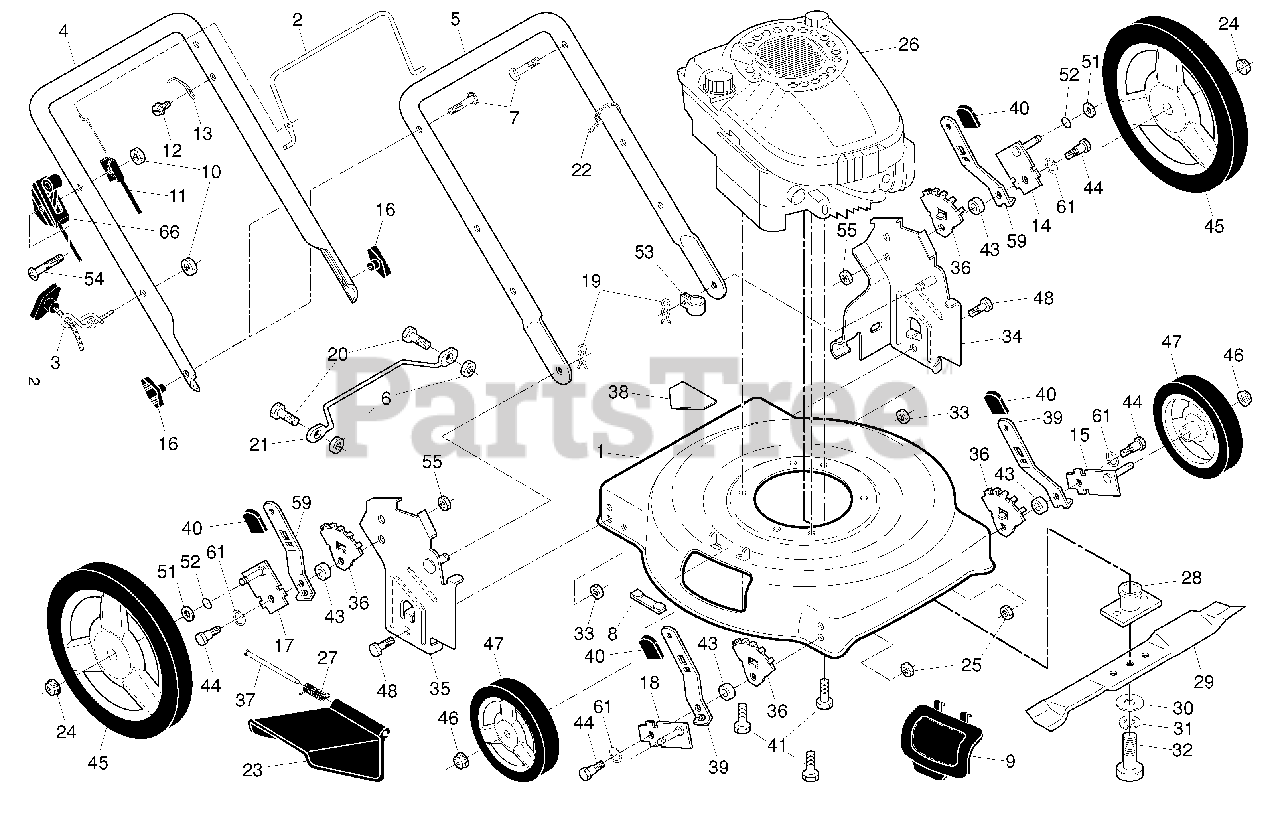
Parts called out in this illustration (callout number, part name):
1	Lawn Mower Housing
2	Control Bar
3	Rope Guide
4	Upper Handle
5	Lower Handle
6	Locknut, Hex 1/4-20
7	Handle Bolt 5/16-18
8	Clip, Closeout
9	Plate, Mulcher
10	Nut, Hex
11	Engine Zone Control Cable
12	Hex Thread Rolling Screw #10-24 x1/2
13	Up-Stop Bracket
14	Axle Arm Assembly (Rear, LH)
15	Axle Arm Assembly (Front, LH)
16	Handle Knob
17	Axle Arm Assembly (Rear, RH)
18	Axle Arm Assembly (Front, RH)
19	Hairpin Cotter
20	Hex Head Screw 1/4
22	Wire Tie
23	Discharge Guard
25	Nut, Hex
26	Engine, Briggs & Stratton, Model Number 122T02 (Order parts from engine manufacturer)
27	Torsion Spring
28	Blade Adapter
30	Hardened Washer
31	Helical Lockwasher 3/8
32	Hex Head Screw 3/8-24 x 1/4 Grade 8
33	Locknut 5/16-18
34	Wheel Bracket, Support, LH
35	Wheel Bracket, Support, RH
36	Wheel Bracket, Adjuster
38	Danger Decal
39	Selector Spring, Front
40	Selector Knob
41	Hex Head Thread Rolling Screw 3/8-16 x 1
44	Shoulder Bolt
45	Wheel & Tire Assembly, Rear 12"
46	Locknut, Hex 5/16-18
47	Wheel & Tire Assembly, Front 8"
48	Hex Head Bolt 5/16-18 x 7/8
53	Clip, Cable
55	Selector Spring, Rear
58	Locknut, Hex 5/16-18
61	Washer, Cylindrical
